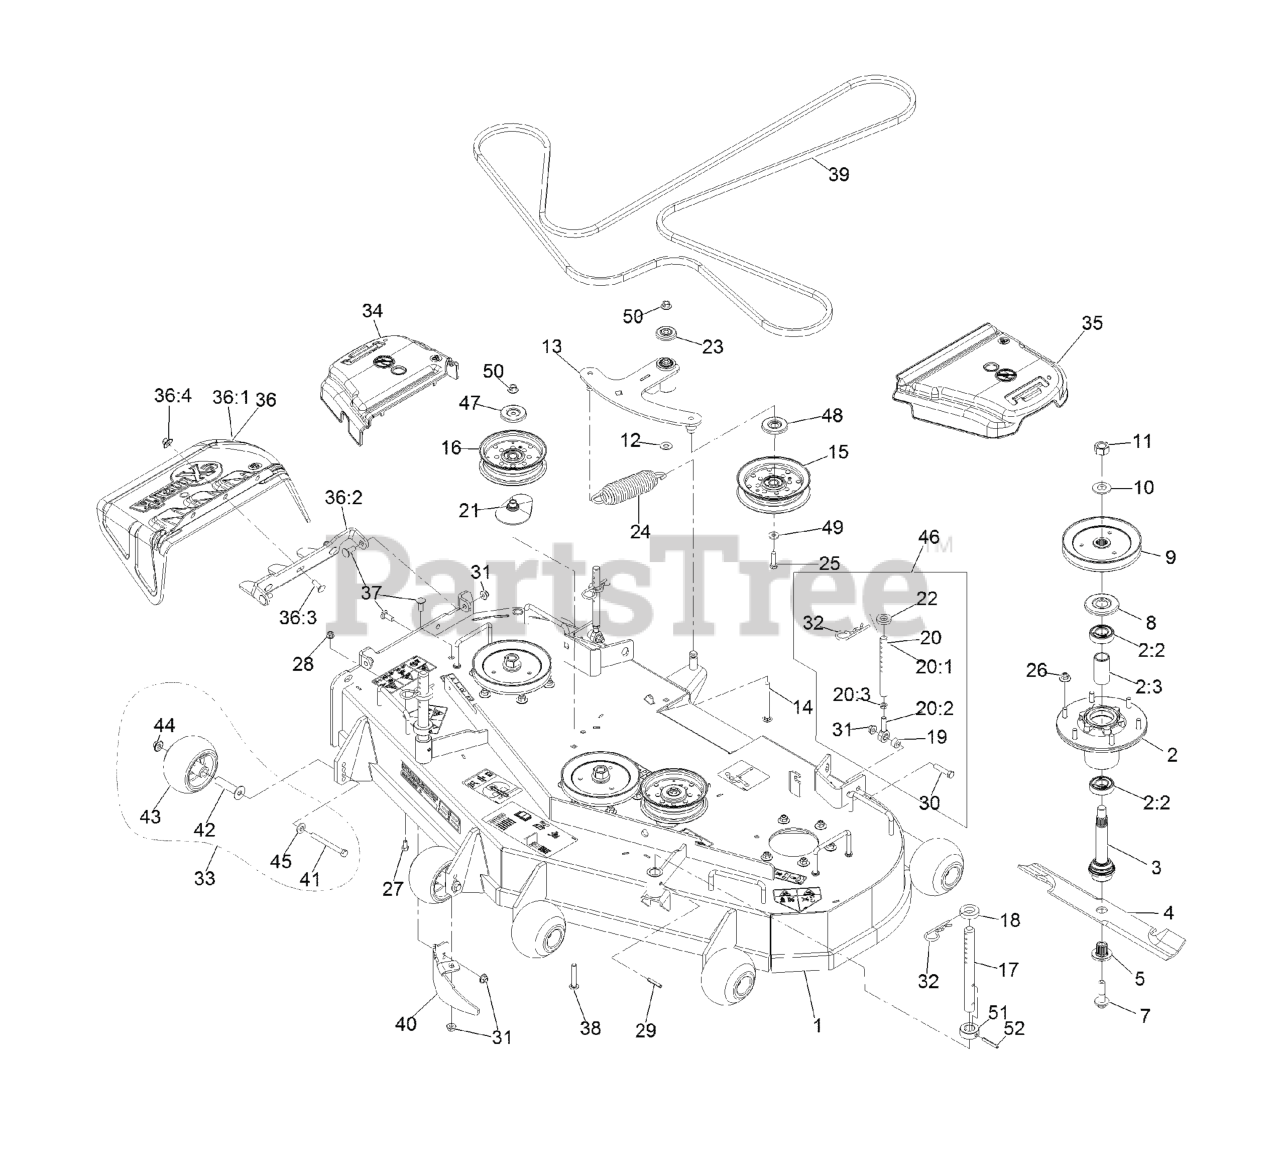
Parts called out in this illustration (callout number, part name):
1	ASM, DECK W/ DECALS, 52
2	ASM-CUTTER HSG WITH BEARINGS
2:2	BEARING-BALL
2:3	SPACER-BEARING
3	ASM-SPINDLE AND SEAL
5	BUSHING,SPLINED
7	SCREW,SEMS 1/2-20 X 2.19
8	GUARD,BEARING TOP .989
9	SHEAVE,BLADE DRIVE 6.50
11	NUT-HEX
12	WASHER-FLAT
13	ASM, DECK IDLER
14	SCREW-CARR
15	IDLER-PULLEY, FLAT
16	IDLER-PULLEY, FLAT 5.00X1
17	ROD, DECK SUPPORT
18	SPACER-DECK SUPPORT
20:1	LINK,SUPPORT
20:2	BALLJOINT
20:3	NUT-HJ
21	SPACER-PULLEY
23	GUARD-TOP
24	SPRING-EXTENSION
25	SCREW-HH
26	Nut-Nyloc 3/8-16 Flg
27	SCREW-HH
28	NUT-HF, NI
30	SCREW-HH
31	NUT-HF, NI
32	PIN,HAIR COTTER
33	KIT, ANTI-SCALP ROLLER
34	COVER-BELT, RH
35	COVER-BELT, LH
36	ASM,DISCHARGE CHUTE
36:1	CHUTE,DISCHARGE
36:2	BRACKET,DISCHARGE CHUTE
36:3	SCREW-CARR
36:4	Nut-Nyloc 3/8-16 Flg
37	SCREW-CARR
38	BOLT-CARR, SHORT NECK
39	BELT, DECK DRIVE
40	BAFFLE-DOGLEG, LZ-VT52
41	SCREW-HH 3/8-16 X 3 3/4 GR 8
42	AXLE, ROLLER
43	ROLLER-SCALP, ANTI
44	Nut-Nyloc 3/8-16 Flg
45	WASHER-BELLEVILLE
46	KIT,SUPPORT LINK W/PIN
47	SHIELD-DUST
48	SHIELD-GUARD, DUST
51	COLLAR, DECK HEIGHT PIN
52	PIN-ROLL
